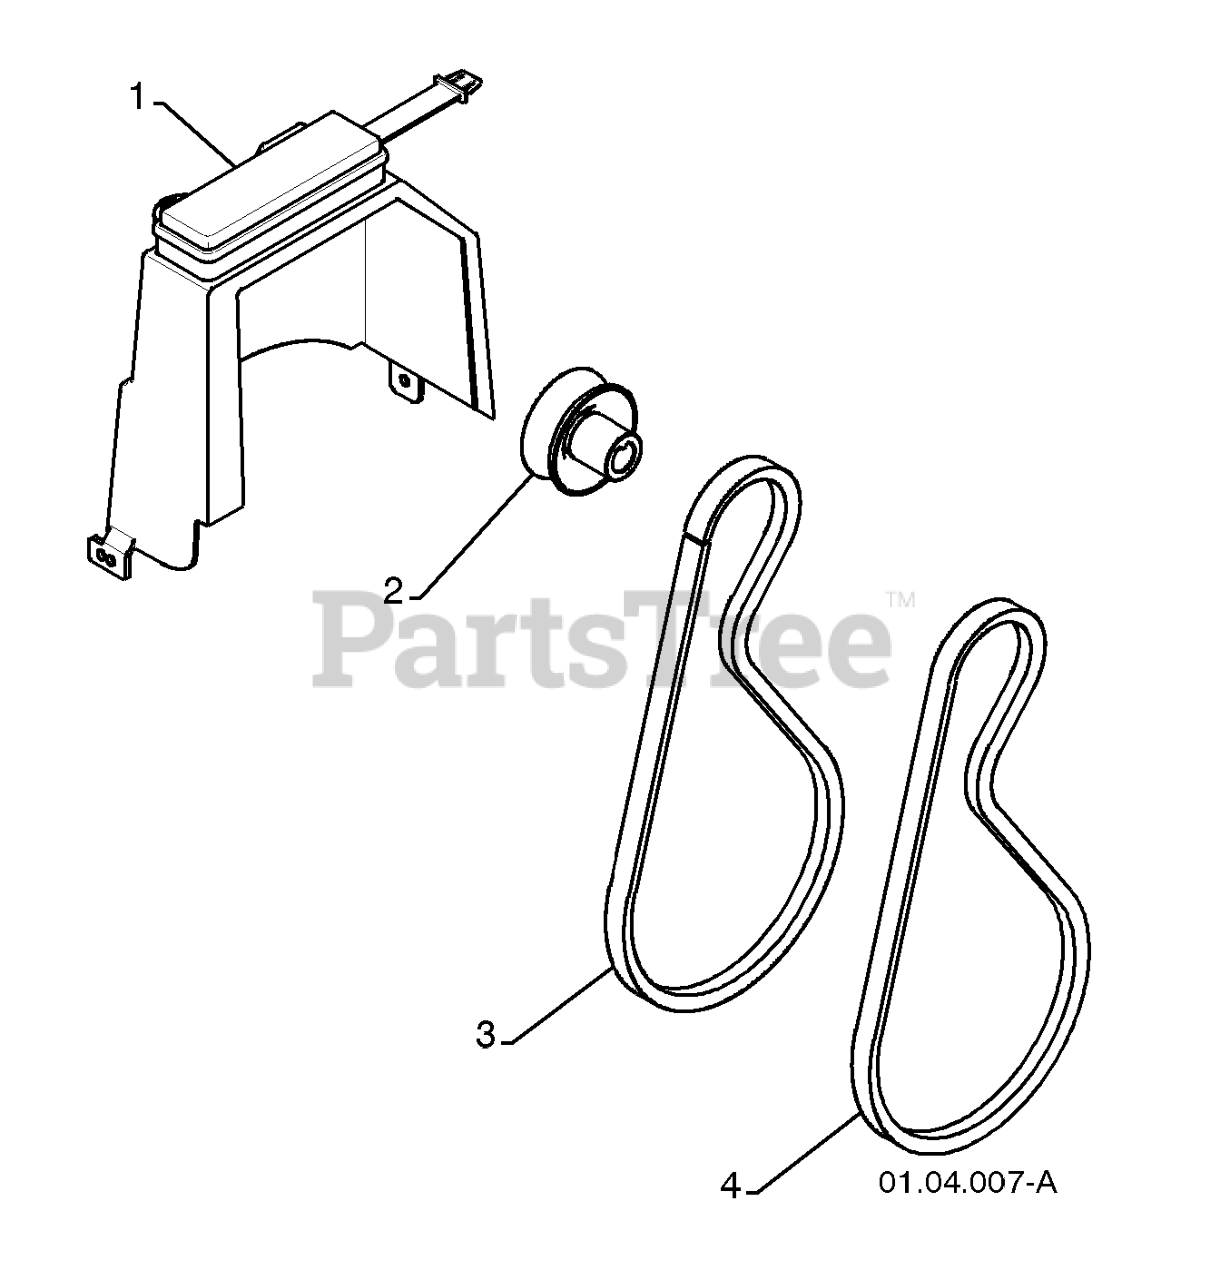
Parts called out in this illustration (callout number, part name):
1	COVER.ASM.BELT/STORAGE
2	PULLEY, ENGINE IMPELLER DRIVE
3	V-BELT TRACTION 34.25
4	BELT.V.IMPELLER.DRIVE
